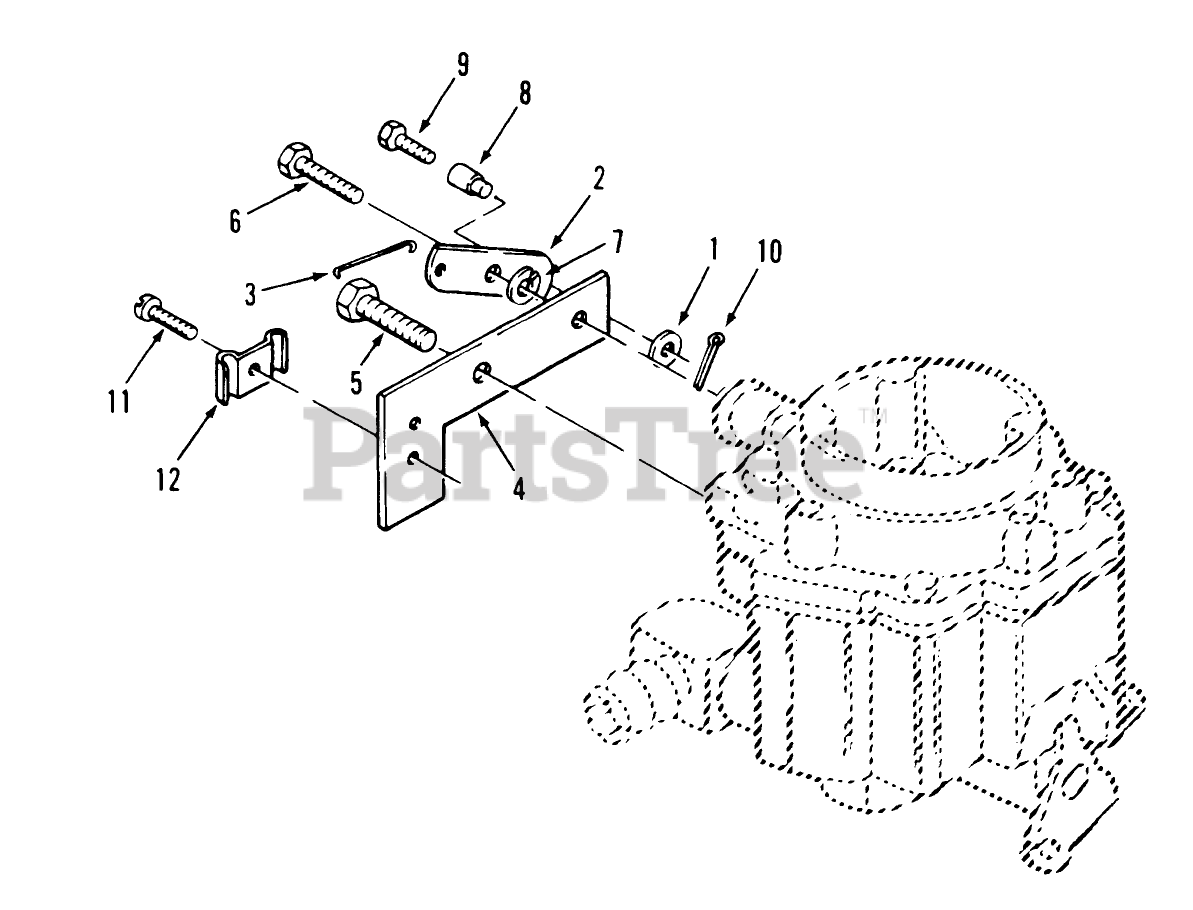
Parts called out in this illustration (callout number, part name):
1	Washer
2	SWIVEL-CHOKE
3	LINK-CHOKE
4	BRACKET
5	SCREW-HWH
6	BOLT-SHOULDER
7	WASHER-LOCK
8	SWIVEL
9	SCREW
10	PIN-COTTER
11	SCREW-TAPPING
